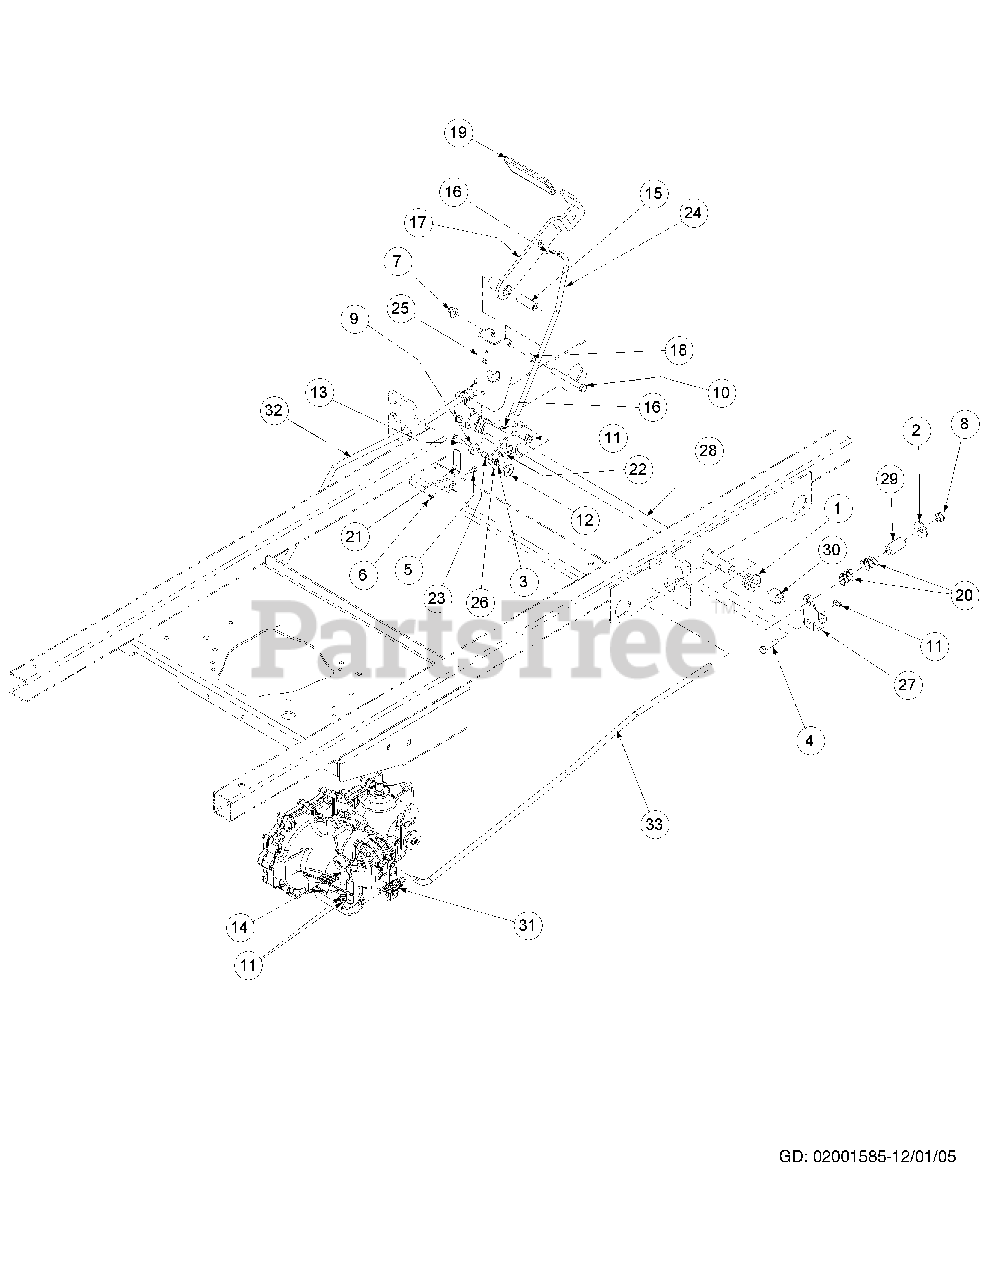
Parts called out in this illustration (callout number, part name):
1	Hex Flange Bearing, .752 ID
2	Washer, 1/2
3	Lock Nut, Nylon Insert, 1/4-20
4	Hex Cap Screw, 5/16-18 x 1-1/2
5	Screw, Hex Washer, 10-32 x 1/2
6	Lock Nut, Nylon Insert, 10-32
7	Nut, Flange Lock, 3/8-16
8	Nut, 7/16-14, Nylock
9	Spacer, Control Rod
10	Hex Cap Screw, 3/8-16 x 3-1/4
11	Nut, Lock, HexFlange, 5/16-18
12	Flat Washer, .406 ID x 1.0 OD x .105
13	Screw, TT, 1/4-20, 1.0, Hex Index Washer
14	Hex Cap Screw, 5/16-18 x 2.75
15	Spacer, .39 ID x .63 OD x 1.75
16	Hair Pin, INT .072 x 1.12 Lg.
17	Weldment, Brake Handle
18	Spacer, .375 x .50 x .75 Lg
19	Grip, Park Brake
20	Lift Handle Spring
21	Spring Retainer
22	Socket Head Capscrew, 5/16-18 x 1.50
23	Spacer, Pump Release
24	Rod Brake, Connect To Handle
25	Park Brake Mounting Bracket
26	Brake Arm Assembly
27	Brake Arm Bracket
28	Pivot Brake Shaft
29	Hose, .5 ID x .78 OD, Low Pressure
30	Spacer, .76 ID x 1.0 OD x 3/4
31	Spring Extension, .740 OD x 2.656
32	Brake Rod, LH
33	Brake Rod, RH
